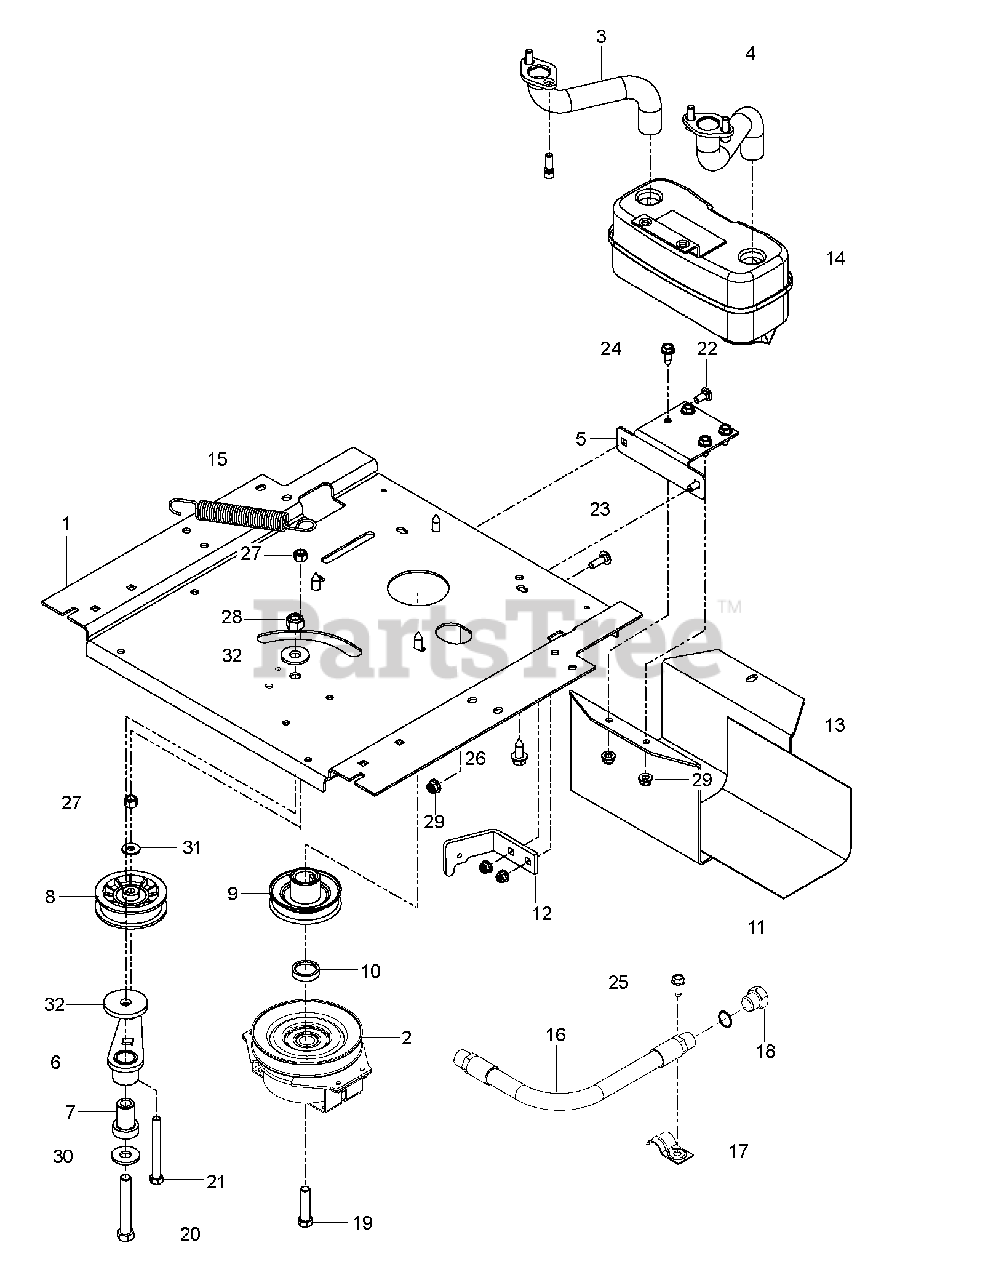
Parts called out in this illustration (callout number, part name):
1	PLATE.ENGINE.PNT.23"FRAME.EDIP
2	CLUTCH.OGURA.5.0PD.GT1.5A-EH07
3	PIPE.EXHAUST.RH.CV18/20
4	PIPE.EXHAUST.LH.CV18/20
5	BRACKET, MUFFLER, BLACK
6	IDLER ARM WELDMENT
7	IDLER SPINDLE
8	PULLEY, IDLER RAKE & ZTR
9	PULLEY.ENGINE
10	SPACER.SPACER.625 W/OGURA.LCC
11	HEAT SHIELD
12	CLUTCH.STOP.OGURA LCC.BLACK
13	GUARD.MUFFLER.WO.TOW.HITCHX431
14	MUFFLER ASM TWIN
15	SPRING, DECK DRIVE
16	HOSE.ASSEMBLY.OIL.DRAIN
18	PLUG OIL DRAIN
19	CLUTCH BOLT7/16-20X2.5 GR524HR
20	HCS 1/2-13 X 3-1/4 GD 5 ZD
21	HCS 3/8-16X3-1/2 TAPBLT GR5 ZD
23	BOLT 5/16-18 X3/4 ZN/YEL GR 5
24	BOLT
25	CAPSCREW.HXHD.FLG.5/16-18X.625
26	SCREW 3/8-16X1
27	NUT 3/8-16 NYLOC
28	NUT.LK.W/WSH.1/2.
29	5/16-18 NYLOC FLANGE NUT
30	WASH USS FLAT 1/2
31	WASHER 5/16 FLAT
32	HEAVY WASHER
